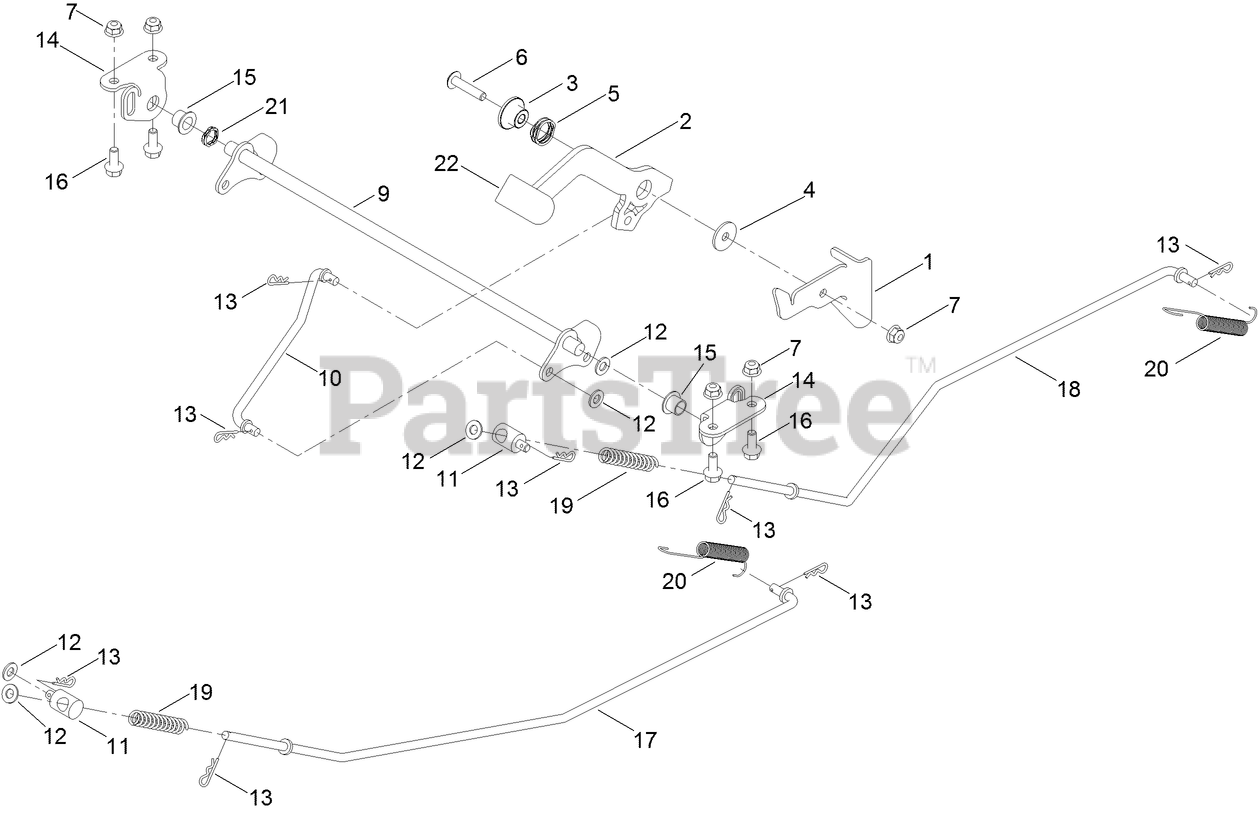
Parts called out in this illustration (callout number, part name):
1	DETENT-BRAKE
2	HANDLE-BRAKE, PARKING
3	BUSHING-FLANGE
4	WASHER-PIVOT
5	WASHER-WAVE
6	SCREW-TORX
7	NUT-HF
9	BELLCRANK-BRAKE
10	ROD-BRAKE, INTERMEDIATE
11	FITTING-ROD
12	WASHER-PLAIN
13	PIN-HAIR
14	PLATE-SUPPORT, BELLCRANK
15	BUSHING-FLANGE
16	SCREW-HHF
17	ROD-BRAKE, RH
18	ROD-BRAKE, LH
19	SPRING-COMPRESSION
20	SPRING-EXTENSION
21	SPRING-WAVE
22	GRIP-HANDLE
